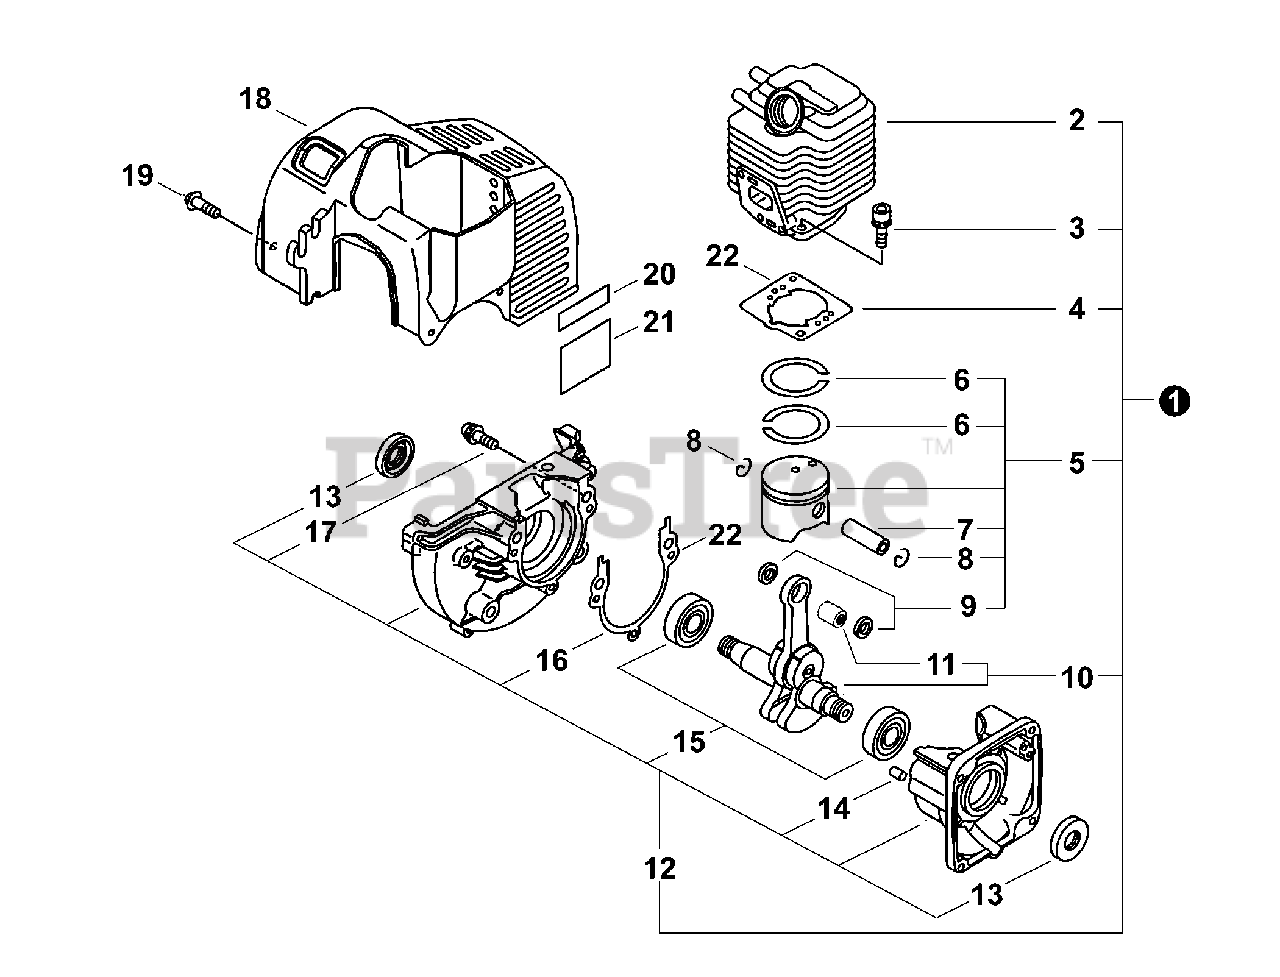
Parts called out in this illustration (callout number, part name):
1	SHORT BLOCK
2	CYLINDER
3	BOLT 5×22
4	GASKET, CYLINDER
5	PISTON KIT
6	RING, PISTON
7	PIN, PISTON 8
8	RING, SNAP
9	WASHER, THRUST
10	CRANKSHAFT ASSY
11	BEARING, NEEDLE 8
12	CRANKCASE KIT
13	SEAL, OIL 12
14	PIN, LOCATING 4×8
15	BEARING, BALL - 6201 C3
16	GASKET, CRANKCASE
17	BOLT 5×28
18	COVER, CYLINDER
19	SCREW 4×12
20	LABEL, CAUTION - HOT
21	LABEL, MODEL
22	GASKET KIT
